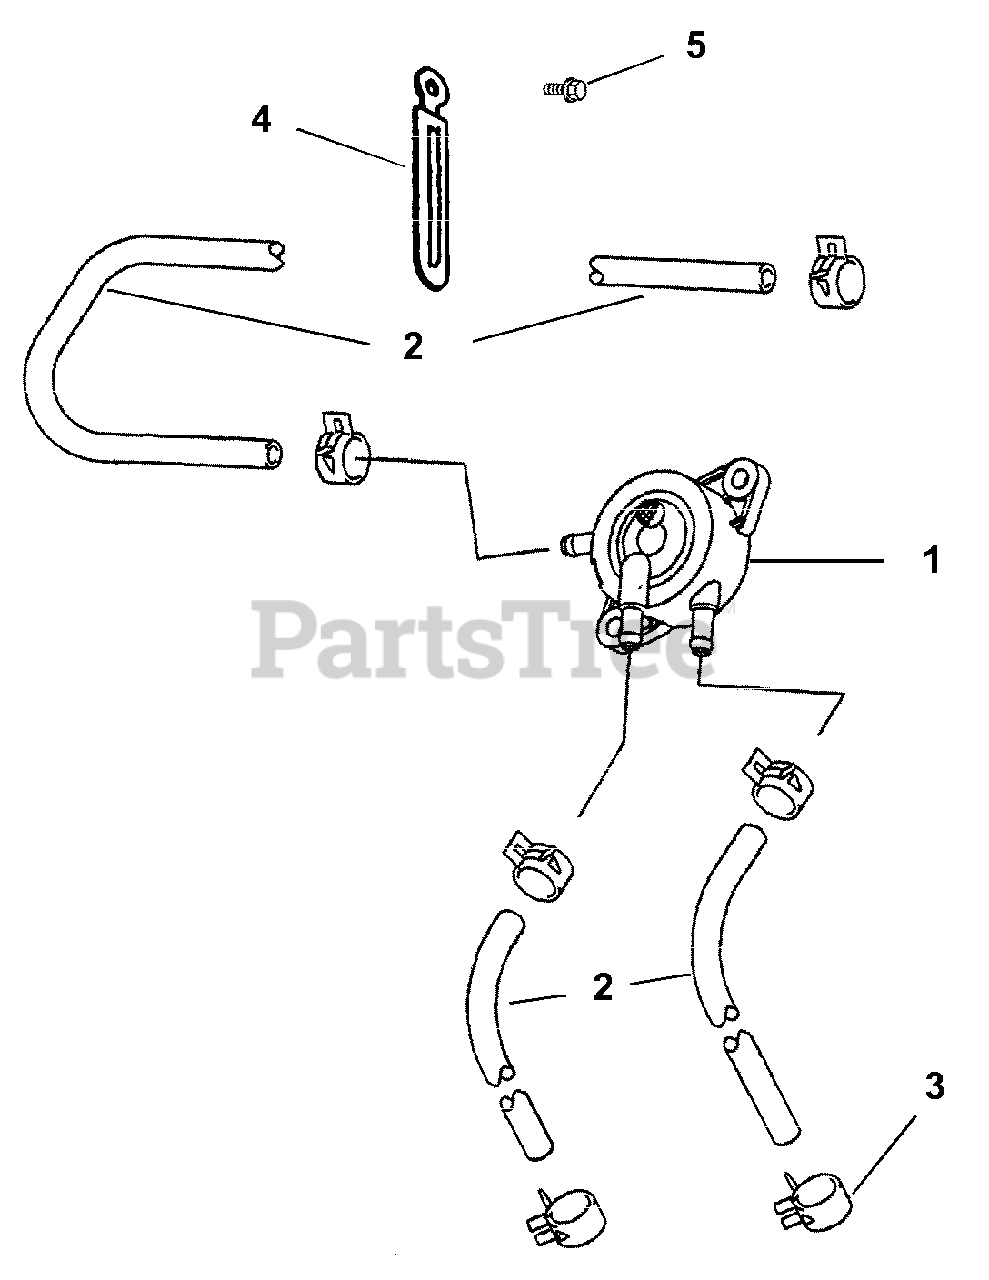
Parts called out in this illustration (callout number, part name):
1	Fuel Pump Ay
2	Fuel Line (39 in./1000mm)
3	Hose clamp
4	Clamp cp
5	Screw
